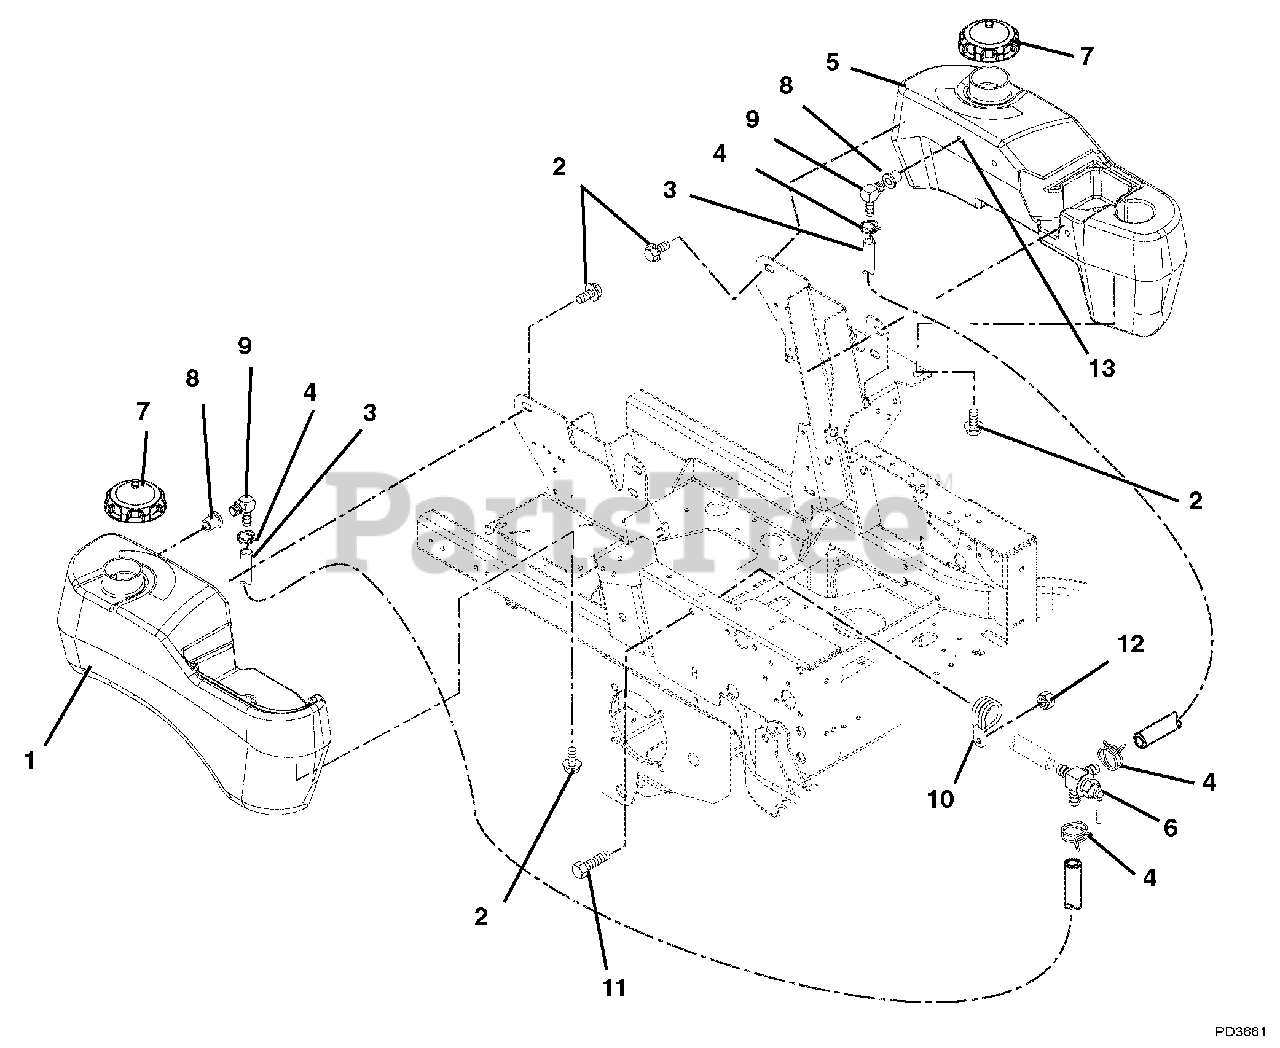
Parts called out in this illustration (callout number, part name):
1	Tank, Gas - Right Hand
2	Bolt, Hex .31-18 x .75 Grade 5
3	Gas Line, Bulk .25" ID
4	Hose, Clamp
5	Tank, Left Hand Fuel (EYE-Q) 100 Series
6	Valve, Fuel
7	Cap, Gas
8	Grommet, Orange (Will not replace black)
9	Fuel Tank Fitting
10	Clamp, Cushioned Steel
11	Bolt, Hex .38-16 x 1.00 Grade 5
12	Nut, Locking Top Flange .38-16
13	Assembly, Medium Tank Fuel Pick-up
